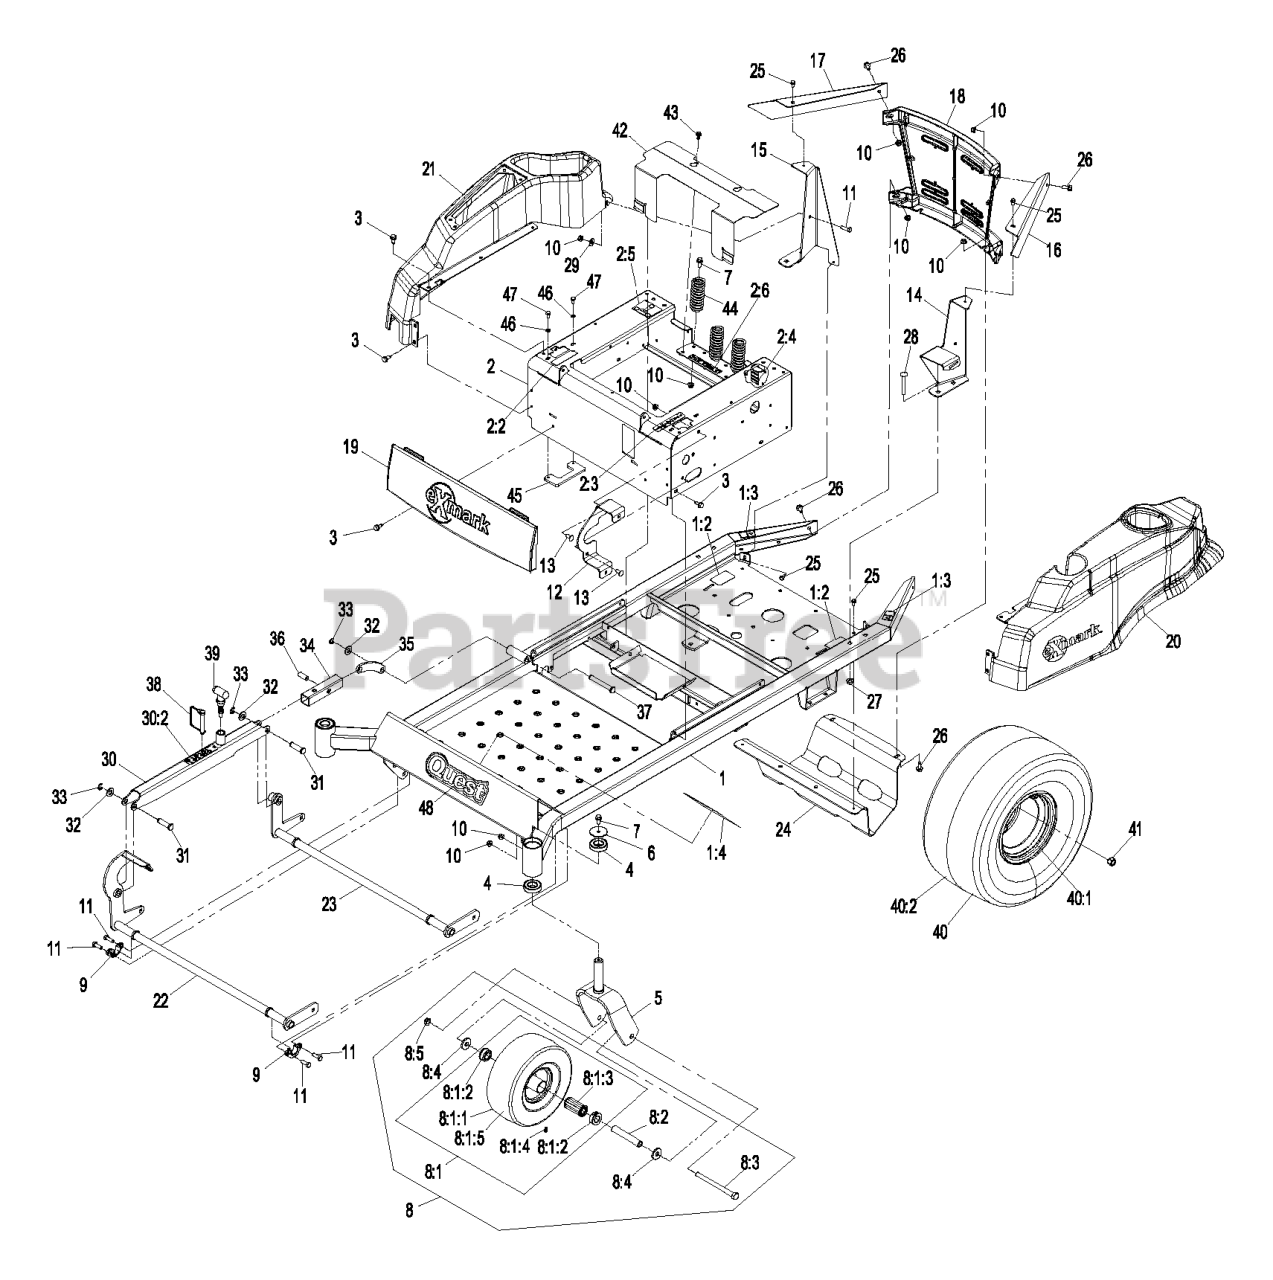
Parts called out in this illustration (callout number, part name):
1	FRAME ASM
1:2	DECAL-DRIVE RELEASE
1:3	DECAL-WARNING
2:2	DECAL-CONTROL, MOTION
2:4	DECAL-FUSE BLOCK
2:5	DECAL-ROUTING, BELT
2:6	DECAL-DANGER
3	Screw-HWH 5/16-18 X 3/4 Tf
4	BEARING-BALL
7	SCREW-HHF
8	CASTER WHEEL ASM
8:1	WHEEL-CASTER
8:1:2	BEARING-OUTSIDE
8:1:3	BEARING
8:1:4	FITTING-GREASE
8:1:5	TUBE-INNER (W/VALVE)
8:2	BUSHING-SPANNER
8:3	SCREW-HH
8:5	NUT-HEX
9	BEARING-FLANGE
10	NUT-HF, NI
11	SCREW-HH
12	BRACKET-TANK MOUNT
13	SCREW-CARR
16	GUARD,ENGINE LH
17	GUARD,ENGINE RH
19	PANEL,FRONT EXMARK
25	SCREW-HWH
26	SCREW-HHF
27	NUT-HF, NI
28	SCREW-CARR
29	WASHER-FLAT
30	HEIGHT ADJUST ASM
31	PIN-CLEVIS
32	WASHER-FLAT
33	RING-RETAINING, EXTERNAL
35	ARM-FLOAT LINK
36	PIN-PIVOT
37	PIN-CLEVIS
38	PIN-HITCH
39	PIN-SPRING
40	WHEEL AND TIRE ASM
40	4 PLY WHEEL AND TIRE ASM
40:1	WHEEL
40:2	TIRE
40:2	TIRE-4 PLY
41	NUT-LUG
42	COVER-HYDRO FAN
43	SCREW-HHF
44	SPRING-COMPRESSION
45	STOP-MOTION CONTROL
46	WASHER-SPRING
47	SCREW-HH
48	DECAL,QUEST LOGO
